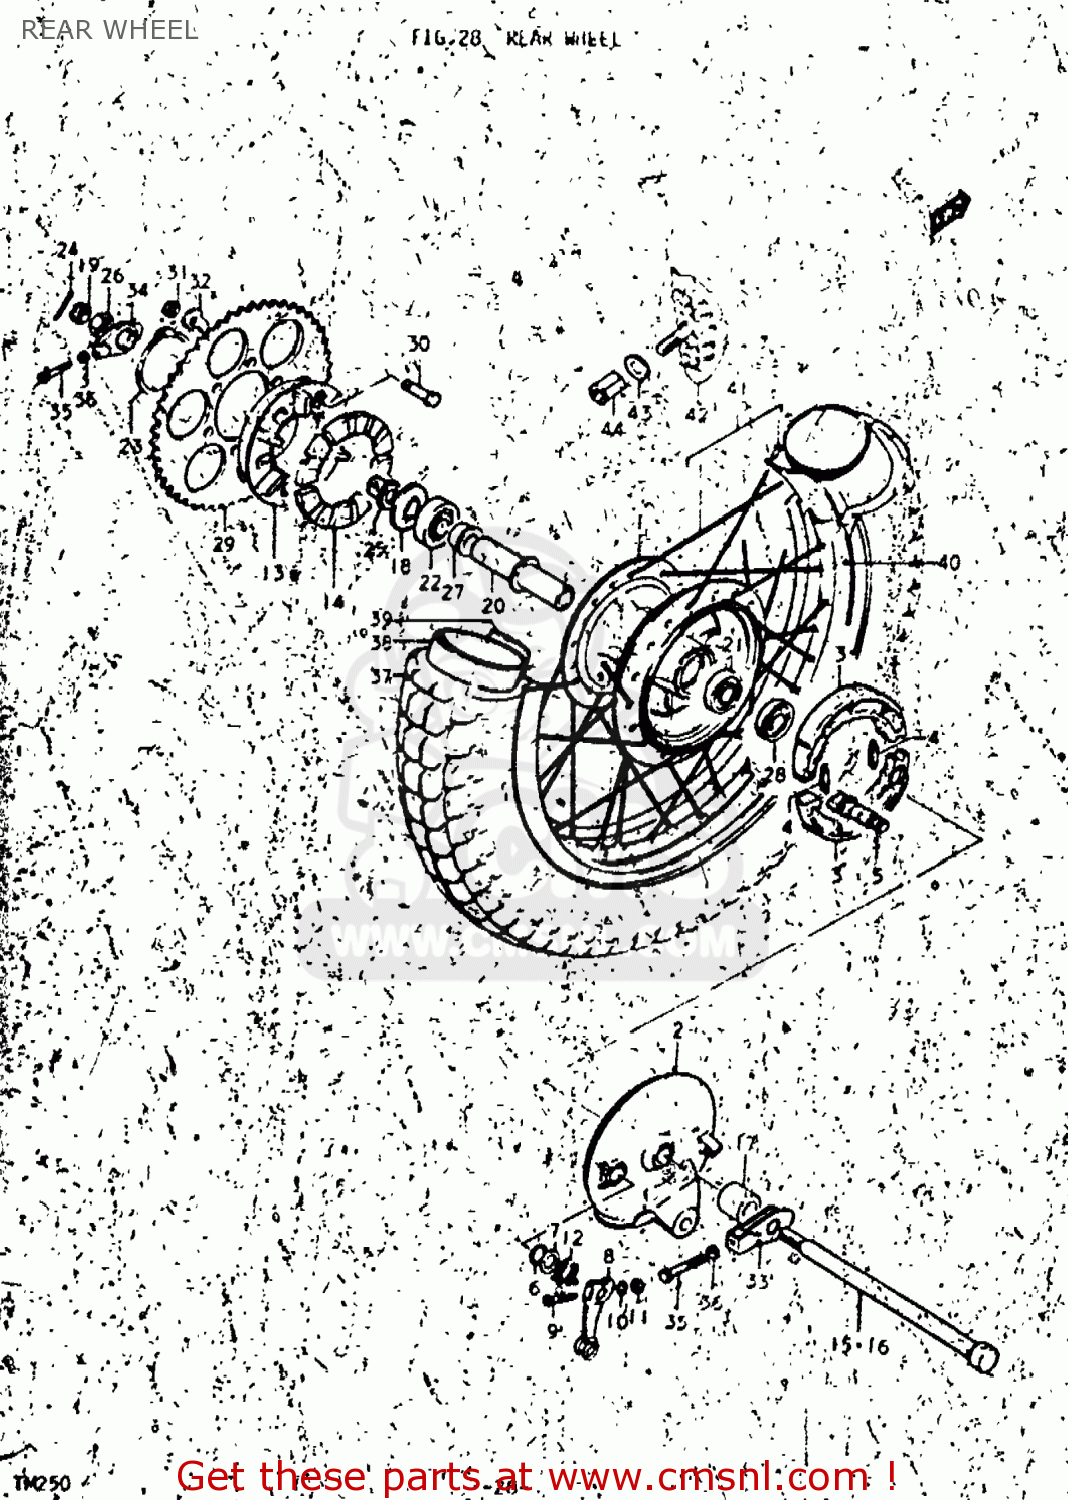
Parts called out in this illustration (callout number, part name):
0	HUB SET,REAR
1	DRUM,REAR HUB
2	PANEL,REAR HUB
3	SHOE,BRAKE
4	SPRING,BRAKE SHOE
5	CAM,FRONT BRAKE
6	O-RING,BOSS
7	WASHER (15X24X1.6)
8	LEVER,REAR BRAKE CAM
9	BOLT
10	WASHER
11	NUT
12	SPRING
13	DRUM,REAR SPROCKET MOUNT
14	ABSORBER,RR WHEEL HUB SHOCK
15	AXLE,REAR
16	AXLE,REAR
17	SPACER
18	SPACER,REAR AXLE,RIGHT
19	NUT
20	SPACER,REAR HUB BEARING
21	BEARING, RH
22	BEARING
23	CIRCLIP
24	PIN 30X40
25	SPACER,REAR AXLE,LEFT
26	NUT
27	SPACER,REAR HUB BEARING
28	OIL SEAL
29	SPROCKET,REAR
30	BOLT(8X33.5)
31	NUT
32	WASHER
33	ADJUSTER,CHAIN
34	ADJUSTER,CHAIN
35	BOLT
36	NUT
37	TIRE
38	TUBE ASSEMBLY,WHEEL,INNER
39	PROTECTOR,WHEEL,INNER
40	RIM,REAR WHEEL
41	SPOKE SET,REAR
42	STOPPER,BEAD
43	WASHER
44	NUT
